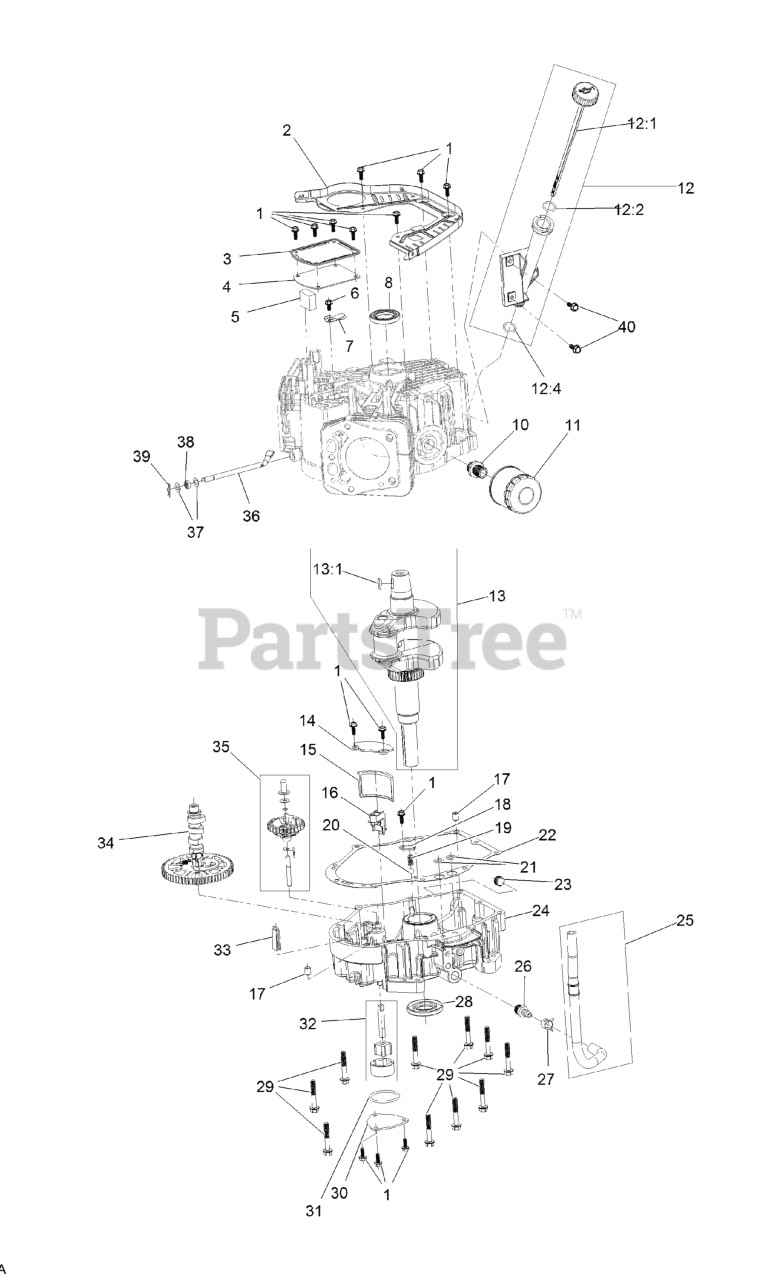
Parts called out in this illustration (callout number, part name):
1	SCREW-HHF
3	COVER-BREATHER
4	GASKET-BREATHER
5	FILTER-BREATHER
6	SCREW-HHF
7	VALVE-BREATHER
8	SEAL-OIL
10	ADAPTOR-FILTER, OIL
11	FILTER-OIL
12	OIL TUBE ASM
12:1	DIPSTICK
13	CRANKSHAFT
13:1	KEY-WOODRUFF
14	COVER-SCREEN, OIL
15	SCREEN-OIL
16	RETAINER-SCREEN
17	PIN-DOWEL
18	PLATE-RETAINER
20	VALVE-BALL
22	GASKET-COVER, CRANKCASE
23	PLUG-DRAIN
24	COVER-CRANKCASE
25	OIL DRAIN HOSE ASM
26	FITTING-HOSE
27	CLAMP-HOSE
29	SCREW-HHF
30	COVER-OIL PUMP
32	OIL PUMP ASM
33	DEFLECTOR-OIL, RUBBER
34	CAMSHAFT
35	GOVERNOR ASM
36	SHAFT-GOVERNOR
37	WASHER-PLAIN
38	SEAL-OIL
39	PIN-HAIR
40	SCREW-HHF
